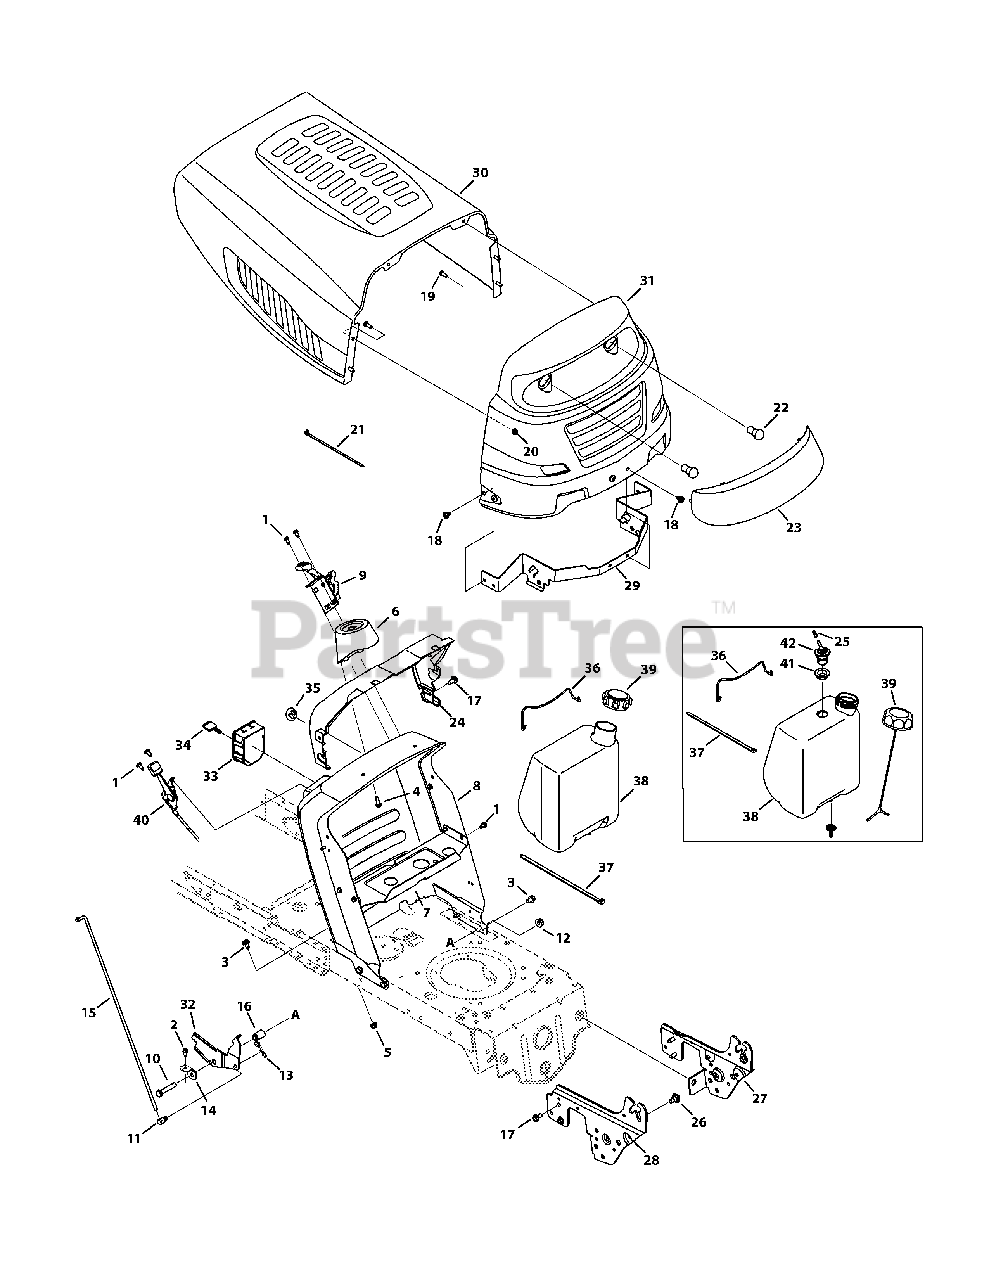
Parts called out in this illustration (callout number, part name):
1	Screw, 1/4-20 x .500
2	Hex Index Washer Screw, 1/4-20 x .500
3	Screw, 5/16-18 x .625
4	Screw, 1/4-15 x .750
5	Flangelock Nut, 5/16-18
6	Steering Support
7	Gas Tank Support Bracket
8	Dash, No RMC
9	Speed Control Assembly
10	Hex Screw, 3/8-16 x 2.0
11	Ferrule, 1/4-20 x 1.0
12	Flangelock Nut, 3/8-16
13	Bow Tie Cotter Pin, 72
14	Speed Latch Tab
15	Speed Selector Control Rod
16	Flange Spacer, .390 x .671 x 1.095
17	Screw, 5/16-18 x .750
18	Screw, 5/16-18 x .375
19	Hex Screw, 1/4-20 x .620
20	Flangelock Nut, 1/4-20
21	Cable Tie
22	Miniature Lamp, 12V
23	Grill Lens
24	Dash Collar
25	Hose Vent, 3/16 EPA
26	Shoulder Screw, 5/16-18, .43 x .29
27	Left-hand Support Pivot Bracket
28	Right-hand Support Pivot Bracket
29	Hood Pivot Bracket
31	Grill
33	Key Switch
35	Choke Plug
37	Cable Tie
38	Fuel Tank, 1.5 Gallon
38	1.36 Gallon Fuel Tank EPA
39	Fuel Cap
39	Fuel Cap, 2.25" EPA
40	Throttle/Choke Cable
41	Rubber Grommet, 23 x 3.55
42	Rollover Valve
